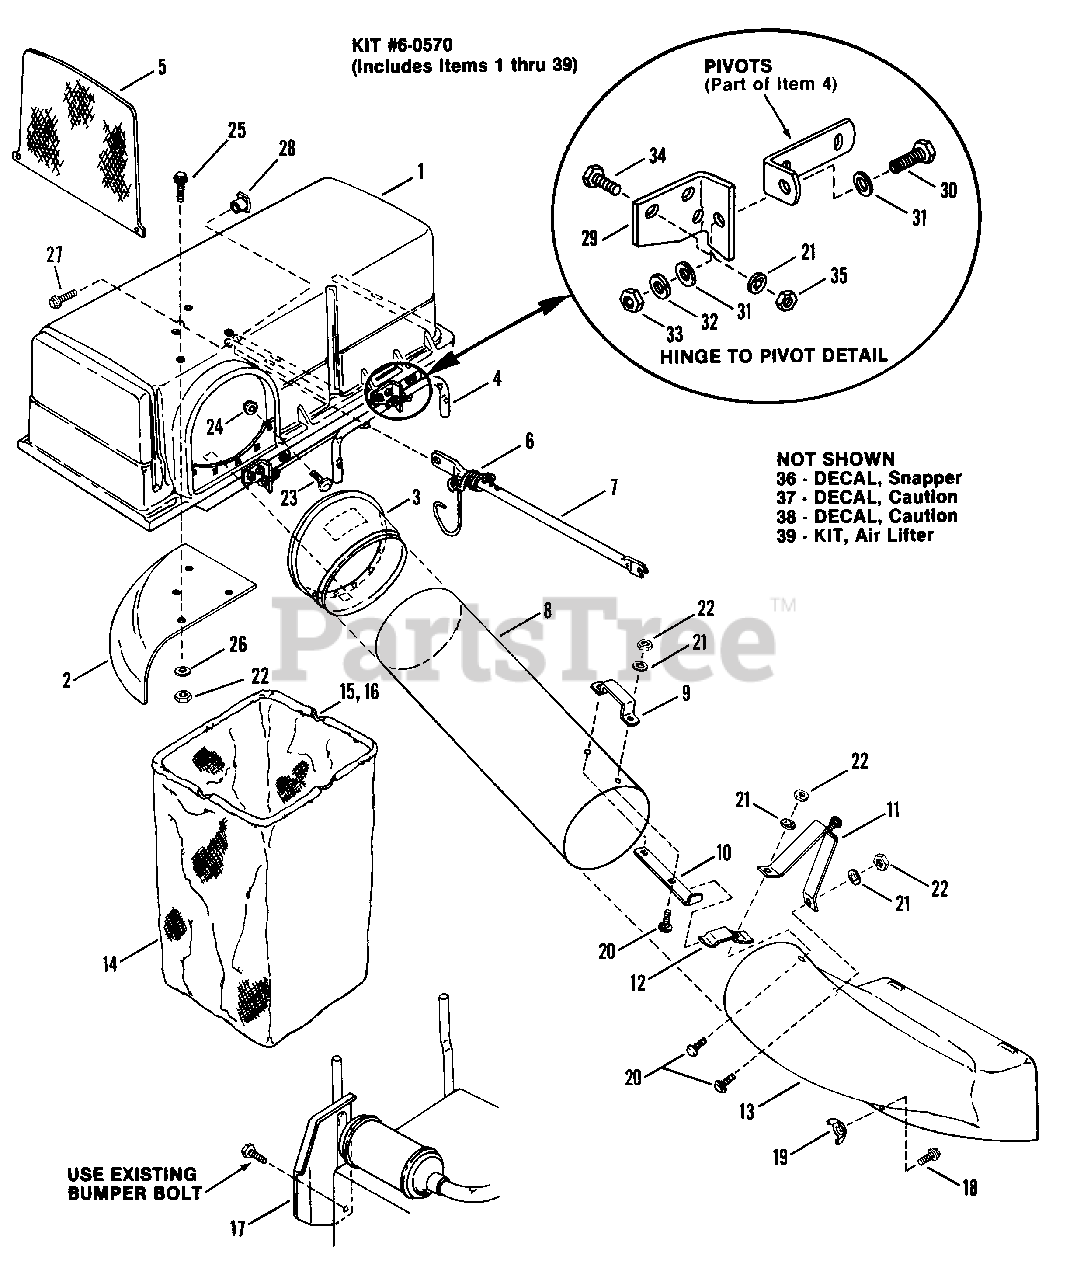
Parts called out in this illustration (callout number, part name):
1	COVER ASSEMBLY
2	SECTOR (Inside Top Baffle)
3	INLET
4	MOUNTING ASSY
5	SCREEN ASSEMBLY
6	SPRING & HOOK ASSEMBLY
7	BRACE
8	TUBE, Grass
9	HANDLE, Tube
10	BASE, Tube Handle
11	BRACKET, Stand-Off
12	LATCH, Tube
13	ADAPTER, (Chute)
14	BAG, Grass Catcher
15	ROD, Bag Support
16	CONNECTOR, Rod
17	SHIELD, Muffler Heat
18	CARRIAGE BOLT, 5/16-18x1" Short Neck
19	WING-NUT, 5/16-18
20	CARRIAGE BOLT, 1/4-20x3/4 Short Neck
21	LOCKWASHER, 1/4 Internal Tooth
22	NUT, 1/4-20 Hex
23	CARRIAGE BOLT, 1/4-20x1/2 Short Neck
24	LOCKNUT, 1/4-20 Flange
25	SCREW, 1/4-20x3/4" Round Hd Machine
26	WASHER, 1/4 SAE (Flat)
27	SCREW, 5/16Cx1-1/2 Flat Head
28	T-NUT, 5/16C
29	HINGE, Top
30	CAPSCREW, 5/16-24x1" Hex Head
31	WASHER, 5/16 SAE (Flat)
32	LOCKWASHER, 5/16 Split
33	LOCKNUT, 5/16-24 Hex
34	CAPSCREW, 1/4-28x3/4" Hex Head
35	NUT, 1/4-28 Hex
